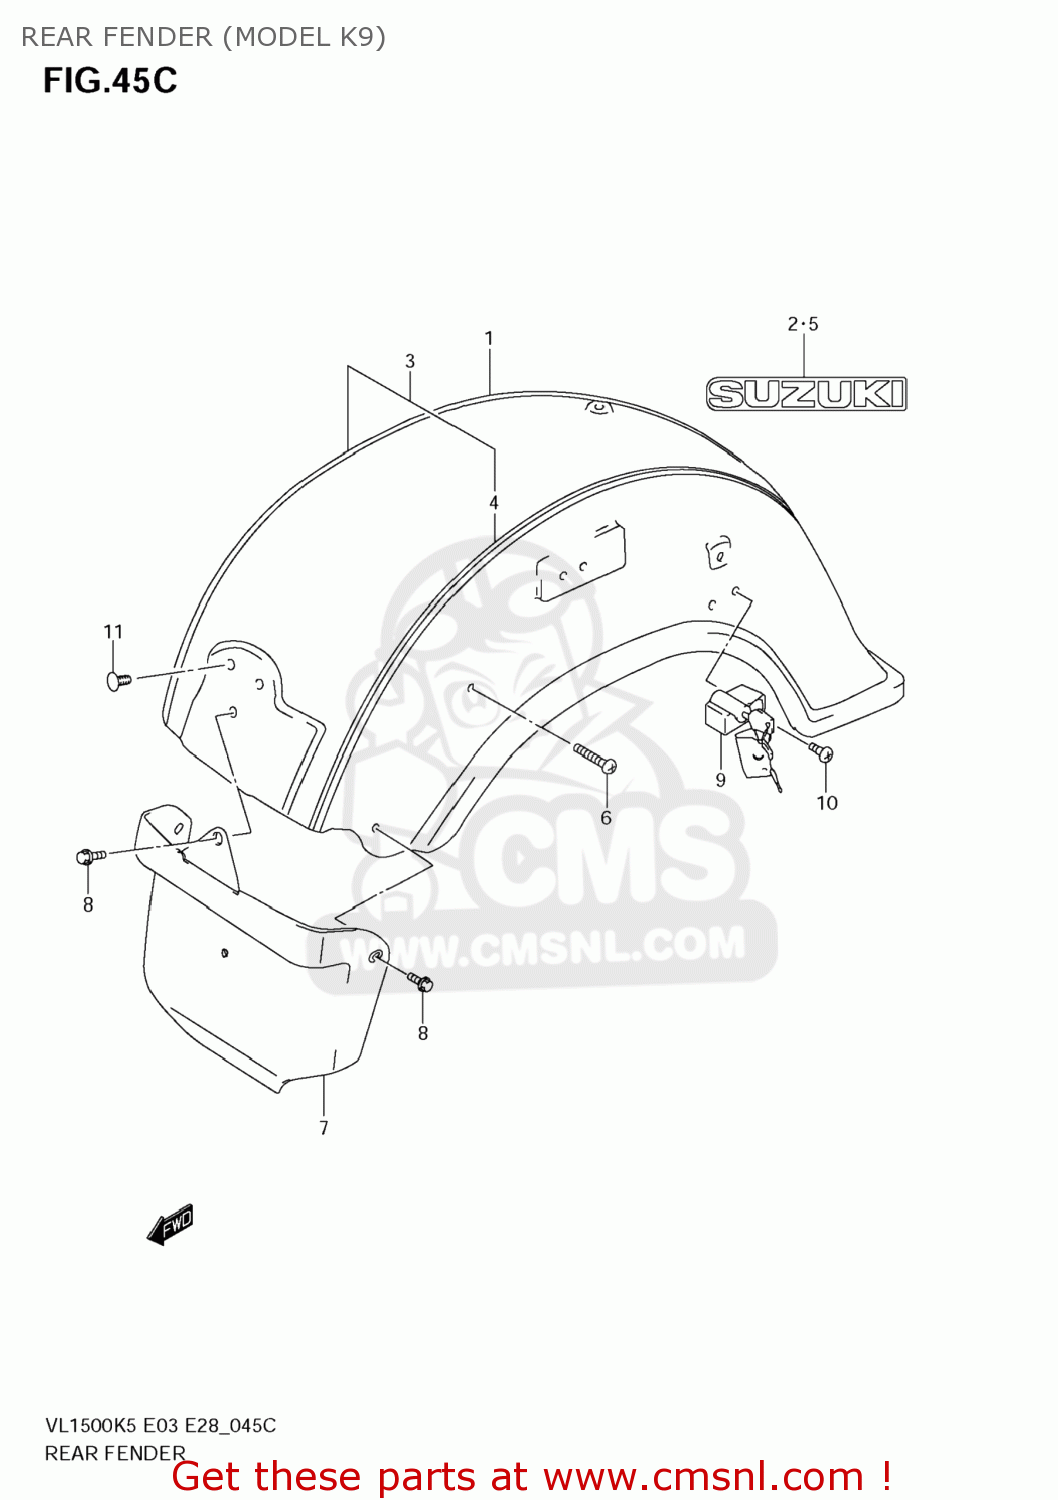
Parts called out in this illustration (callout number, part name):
1	FENDER ASSY,RR
2	EMBLEM,SUZUKI
3	FENDER ASSY,RR
4	TAPE SET,RR FENDER
5	EMBLEM,SUZUKI
6	BOLT(8X37)
7	MUDGUARD,RR FENDER FR
8	BOLT(6X16)
9	LOCK SET,HELMET
10	SCREW(6X14)
11	CAP(OD:12)
